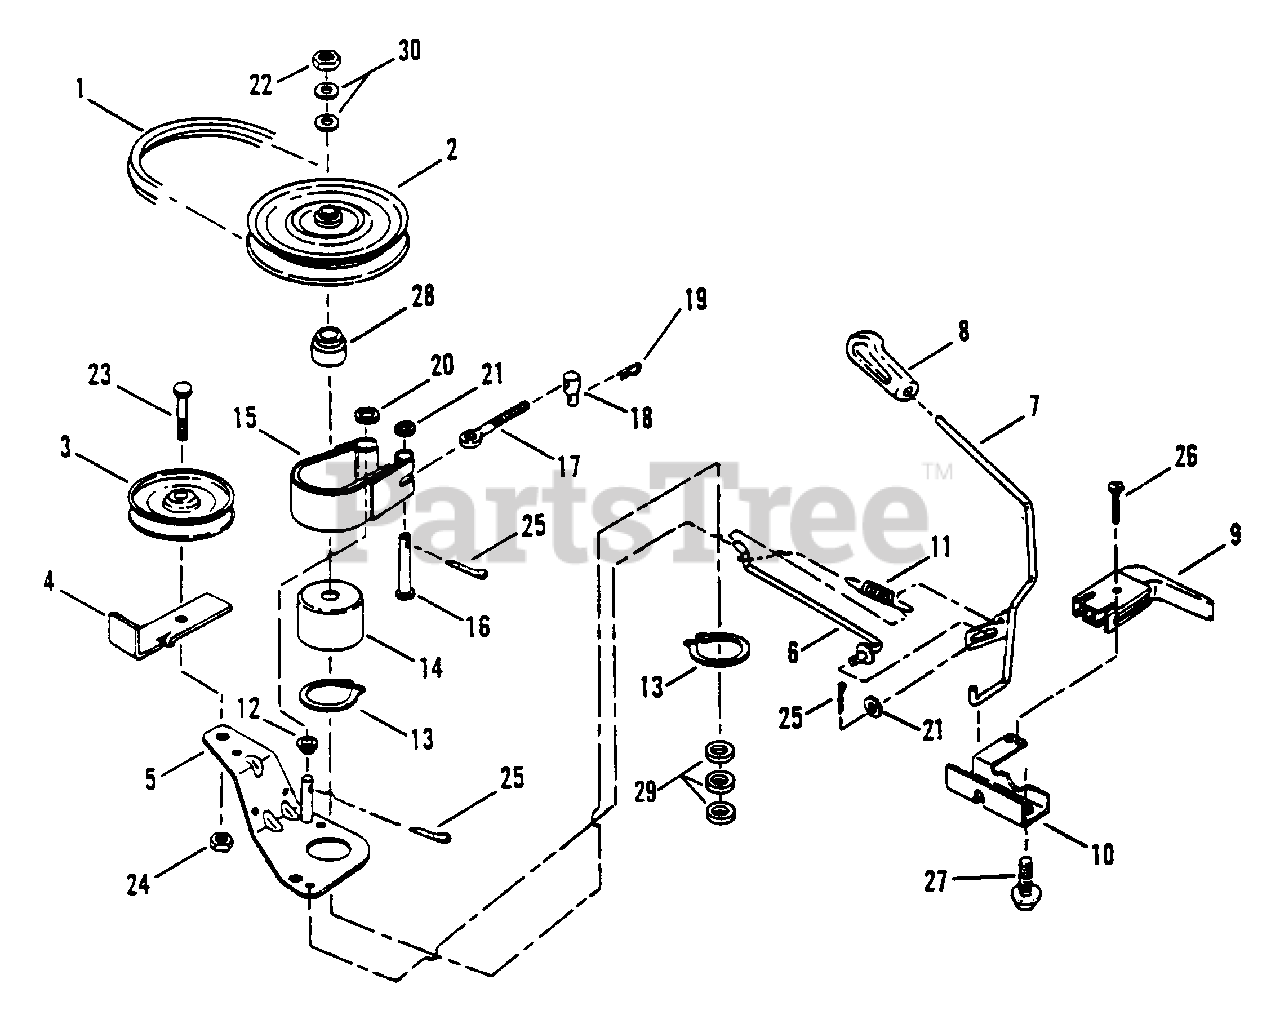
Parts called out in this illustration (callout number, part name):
1	BELT, Drive
2	PULLEY, Spindle
3	PULLEY, Idler
4	RESTRICTOR, Belt
5	ARM, Idler
6	ROD, Idler
7	HANDLE, Blade Lever (On - Off)
8	GRIP, Handle
9	SWITCH, Deck Interlock
10	MOUNT, Handle
11	SPRING, Blade Handle
12	SPACER
13	RING, 2" External Retaining
14	DRUM, Brake
15	BAND, Brake
16	PIN, 1/4 x 1 5/8" Clevis
17	BOLT, 5/16-18 x 3" Eye
18	SWIVEL, Adjustable 1.6
19	PIN, 3/32 x 1 1/2 Hair
20	WASHER, 3/8" Flat
21	WASHER, 1/4 Flat
22	NUT, 3/4-16 Hex Jam
23	SCREW, 3/8-24 x 1 3/4" Hex Cap
24	NUT, 3/8-24 Hex Lock
25	PIN, 3/32 x 3/4" Cotter
26	SCREW, #10-32 x 1" Self-Tap
27	SCREW, 1/4-20 x 5/8" Self-Tap
28	HUB, Pulley
29	WASHER, Spindle
30	WASHER, 49/64 x 1-1/2" Flat
